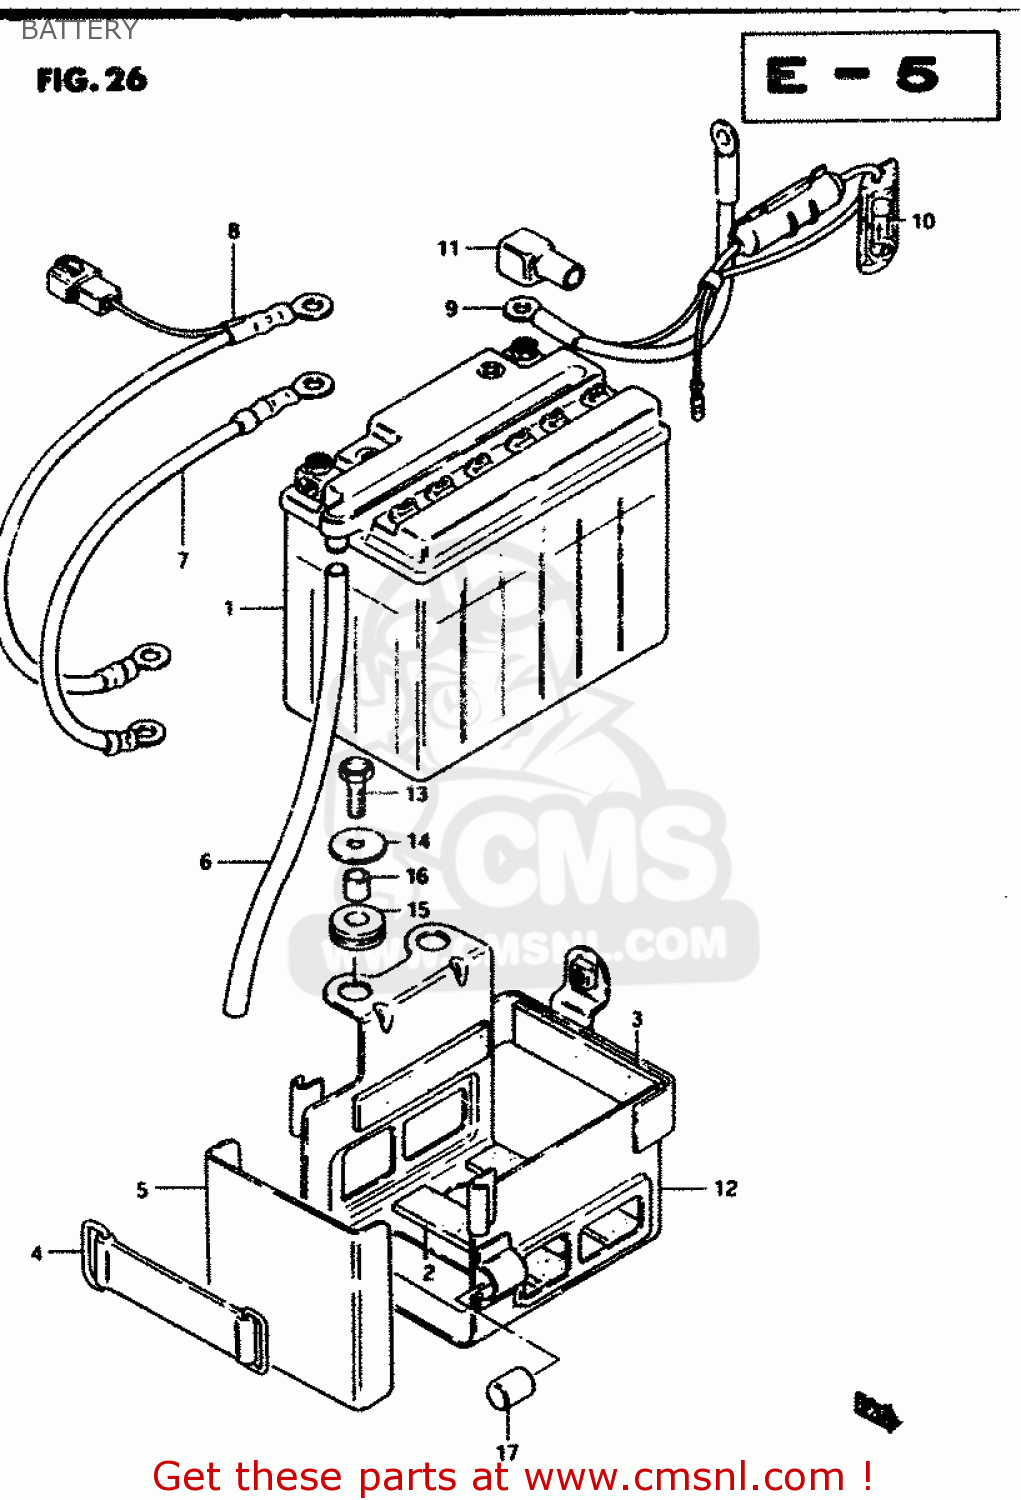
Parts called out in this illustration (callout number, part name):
1	BATTERY(YB12B-B2,12V11.6A)
2	PROTECTOR(20X90)X4
3	PROTECTOR,20X9
4	BAND
5	COVER,BATTERY
6	HOSE,BATTERY EXHAUST
7	LEAD WIRE,BATTERY(-)
8	CORD,BATTERY MINUS
9	FUSE CASE AND PLUS CABLE
10	FUSE(15A)
11	CAP,TERMINAL
12	HOLDER,BATTERY
13	BOLT
14	WASHER
15	CUSHION
16	SPACER (6.1X9X9)
17	CUSHION
